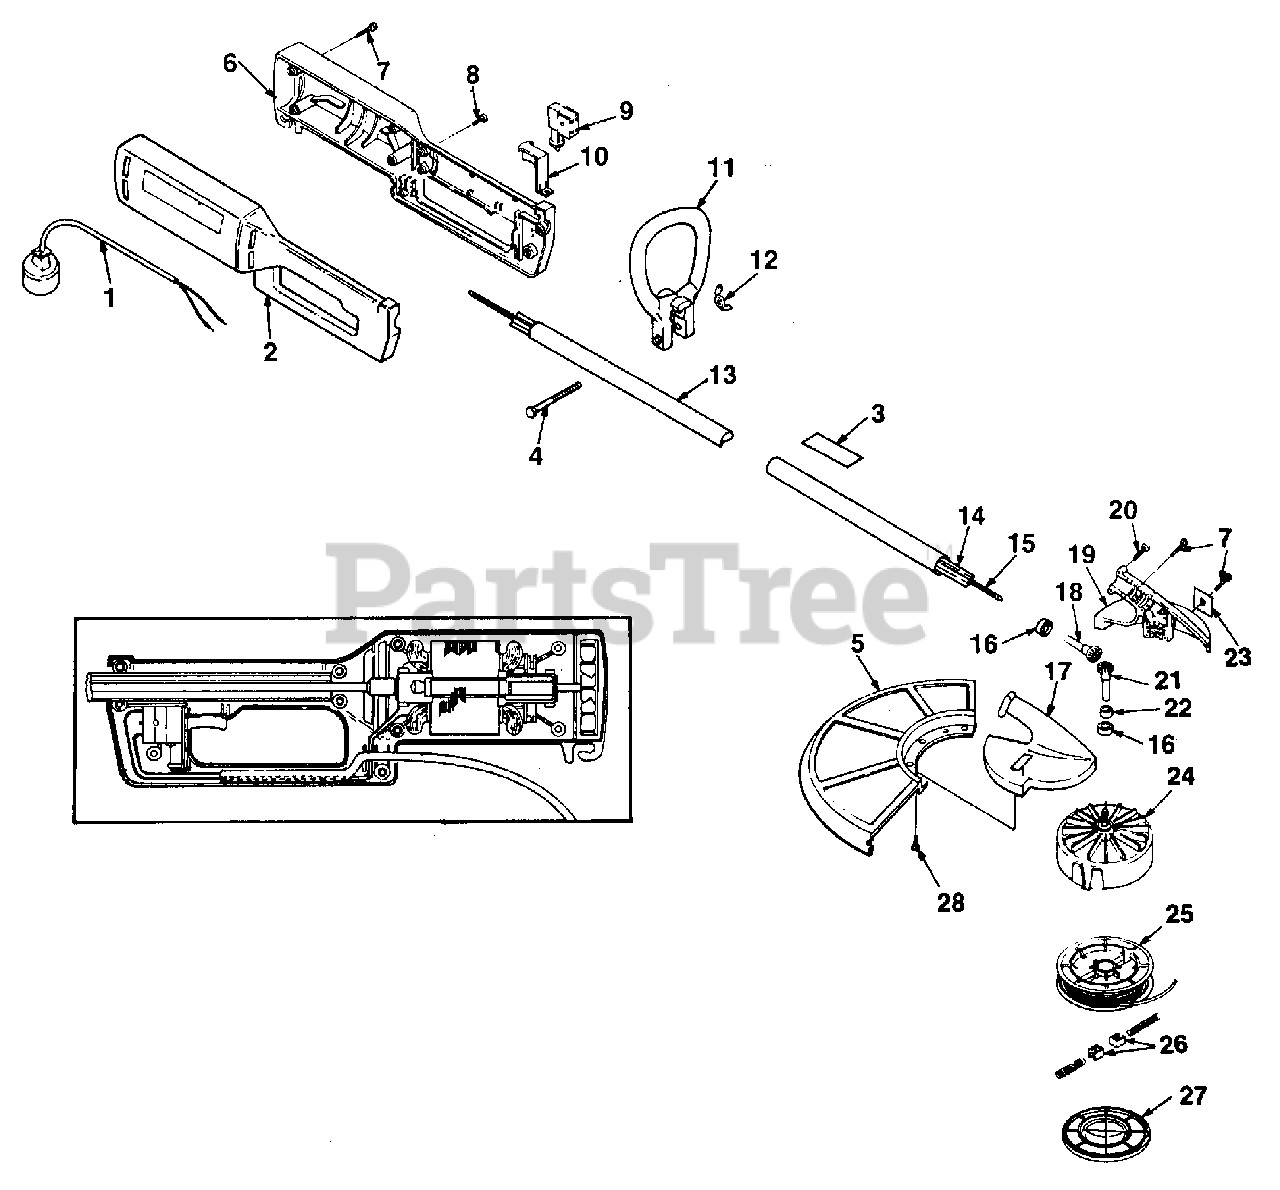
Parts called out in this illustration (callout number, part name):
1	CORD SET
2	HOUSING- Motor (right)
3	LABEL- Warning
4	SCREW- Hex hd. 1/4-20 x 2
5	STRING GUARD w/Cut-off blade
6	HOUSING- Motor (left)
7	SCREW- Thd. forming 10-16 x 3/4
8	SCREW- Thread forming #10-16 x 9/16
9	SWITCH
10	TRIGGER- Switch
11	HANDLE- Front
12	NUT- Wing
14	TUBE- Liner
15	SHAFT- Flexible
16	BEARING
17	HOUSING- Gear (Right)
18	GEAR- Drive
19	HOUSING- Gear (Left)
21	GEAR- Driven
22	BEARING- Flange
24	STRINGHEAD & EYELET ASSY. w/Drive Connector
25	SPOOL & STRING
26	SLIDE & SPRING KIT
27	RETAINER- Spool
28	SCREW- Thread forming #10-14 x 1/2
